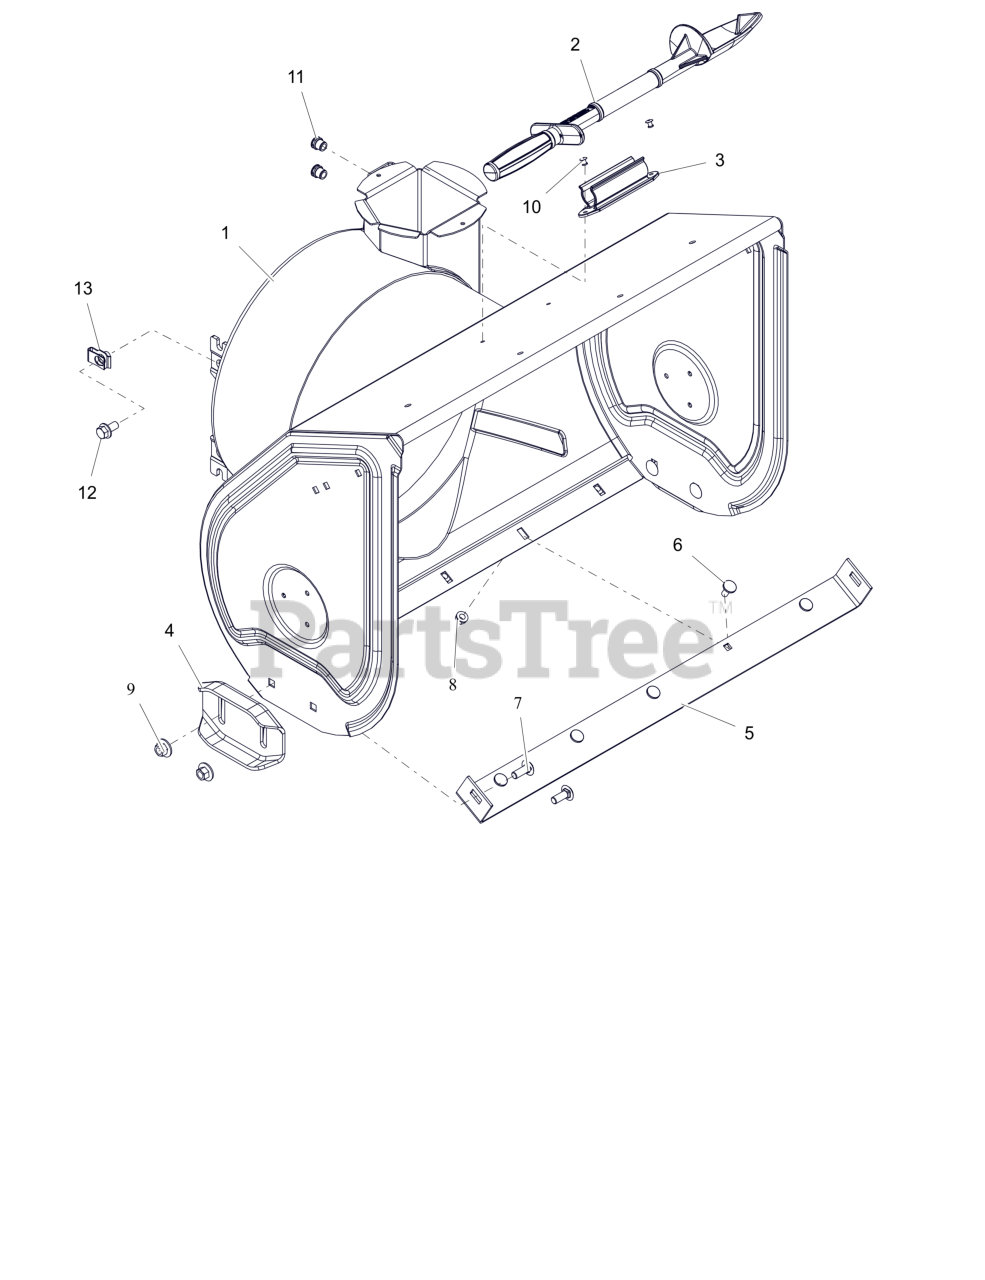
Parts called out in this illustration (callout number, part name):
1	HOUSING, BLOWER W/SAFETY DECALS 28"
2	DEVICE, SNOW CLEAN OUT
3	MOUNT, SNOW CLEAN OUT
4	SKID SHOE, REVERSIBLE - ORANGE
5	BLADE, SCRAPER - 28"
6	BOLT, MODIFIED HEAD CARRIAGE
7	BLT,RHSSN .38-16X1.00 G5 ZCC
8	NUT-LK-TOP-FLG .312-18 GF ZCC
9	NUT- CON-LN .375-16 ZC120
10	RVT, POP .1875 ZCC
11	NUT,THD,INSERT .38-16 ZC120
13	NUT-RTNR .375-16X.37
